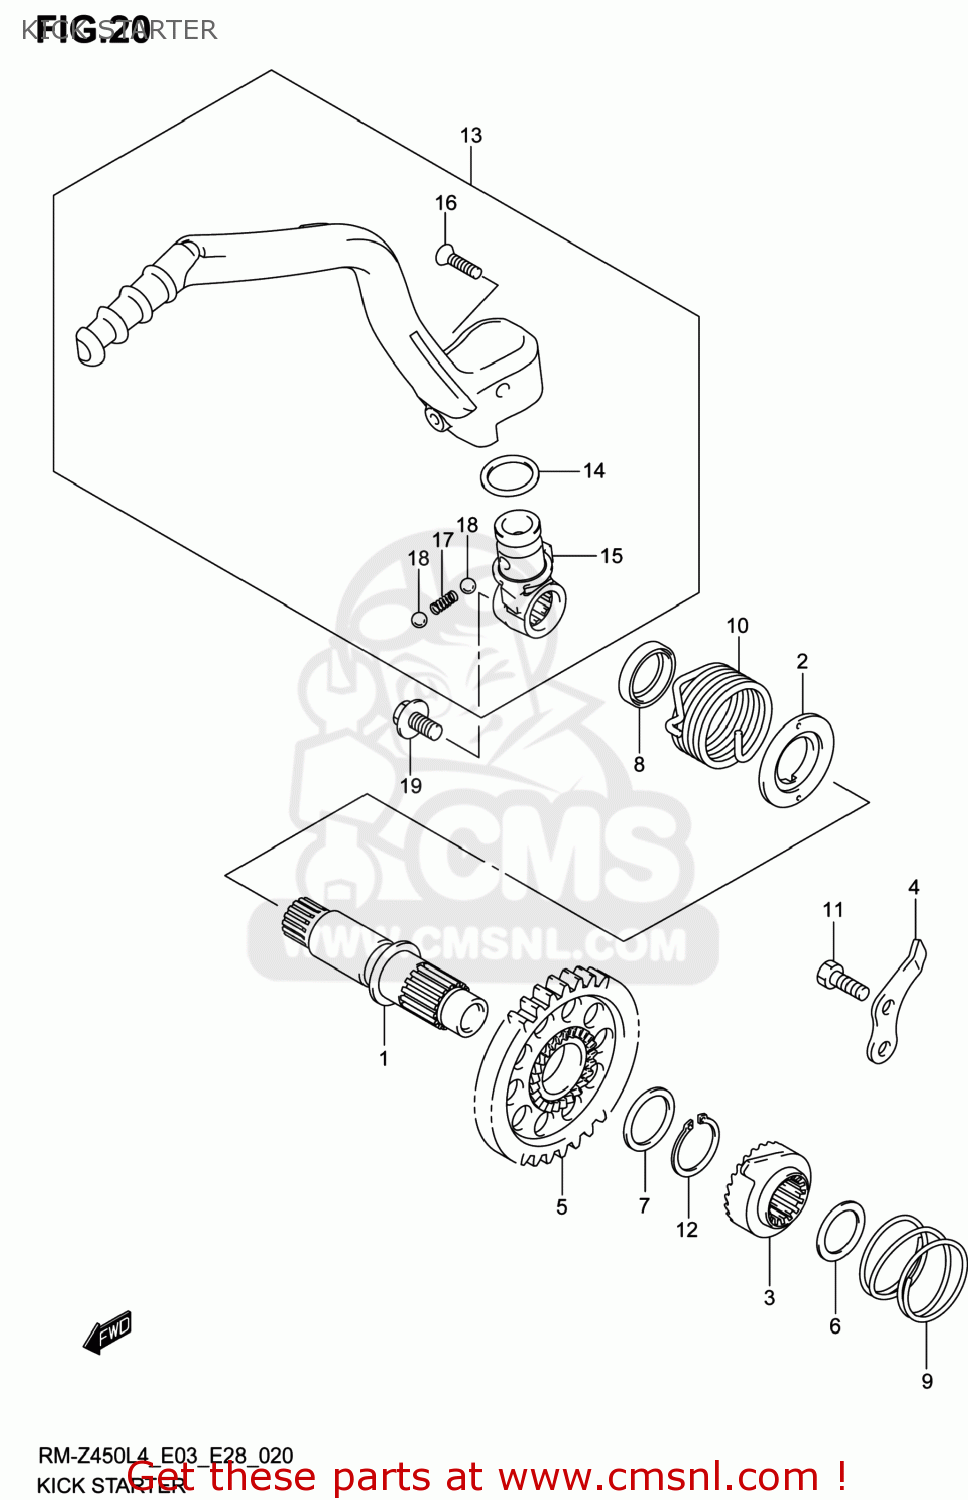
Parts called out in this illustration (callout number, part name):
1	SHAFT,KICK STARTER
2	GUIDE,KICK STARTER SFT SPRING
3	STARTER,KICK
4	GUIDE,KICK STARTER
5	GEAR,KICK STARTER DRIIVE
6	SHIM(17X24X0.5)
7	SHIM(20X26X1)
8	SEAL,OIL(20X27X5)
9	SPRING
10	SPRING
11	BOLT
12	CIRCLIP
13	LEVER ASSY,KICK STARTER
14	O RING,KICK STARTER
15	JOINT,KICK STARTER LEVER
16	SCREW(6X27.5)
17	SPRING
18	BALL
19	BOLT(8X14)
